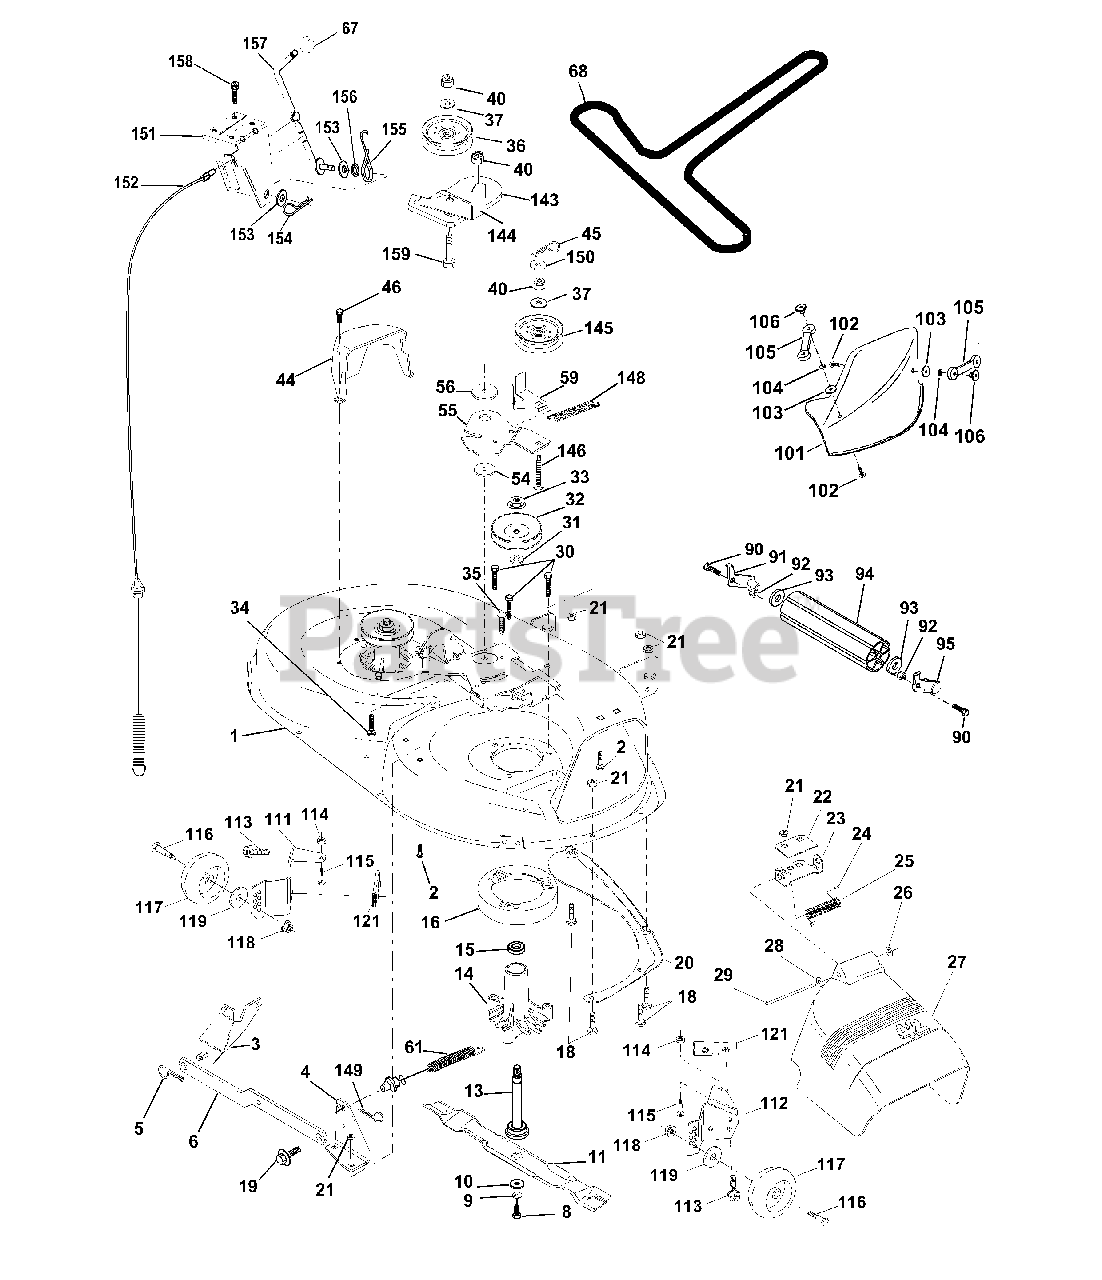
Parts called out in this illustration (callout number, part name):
1	Mower Deck Assembly, 42"
2	Bolt
3	Bracket Asm Fr. Sway Bar 3/42
4	Bracket Asm Deck 42" Sway Bar
5	Retainer Spring
6	Arm, Suspension, Rear
8	Bolt 3/8-24 x 25 Grade 8 patched
9	Washer, Lock
10	Washer,Hardened
11	Blade, Mulching 42"
11	Blade Mower 42" Hi-Lift
13	Shaft Assembly, Mandrel, Vented
14	Housing, Mandrel, Vented
15	Bearing, Ball, Mandrel
16	Stripper, Mandrel Deck
18	Bolt, Carriage 5/16-18 x 5/8
19	Bolt, Shoulder
20	Baffle, Vortex
21	Nut
22	Stiffener Bracket
23	Bracket, Deflector Mower 42"
24	Cap, Sleeve 80 x 112 Blk Mower
25	Spring, Torsion, Deflector 2 52
26	Nut, Push Phos & Oil
27	Shield, Deflector 42" Blk
28	Washer 11/32 x 5/8 x 16 Gauge
29	Rod, Hinge 42" 6 75 W/G
30	Screw Thdrol Washer Head
31	Washer, Spacer Mower Vented
32	Pulley, Mandrel
33	Nut, Toplock 9/16
34	Bolt
35	Fastener, Christmas Tree
36	Pulley, Idler, Flat
37	Washer 13/32 x 13/16 x 16 Gauge
40	Nut
44	Guard, Mandrel, LH
45	Retainer
46	Screw, Thdrol 1/4-20 x 5/8 T
48	Washer,Hardened
49	Roller Assembly, Cam Follower
50	Bolt, Shoulder #10-24 Grade 5
51	Locknut
52	Bolt, Shoulder 5/16-18 UNC
53	Arm Assembly, Pad, Brake
54	Washer,Hardened
55	Arm, Idler
56	Spacer, Retainer
59	Guard TUV Idler
67	Knob
68	V-Belt, 42" Mower
90	Bolt Fin Hex 3/8-16 Unc x 1
91	Bracket Asm. Noseroller LH
92	Nut, Lock, Hex W/Ins 3/8-16 UNC
93	Washer 17/32 x 7/8 x 16 Ga.
94	Roller, Nose
95	Bracket Asm. Noseroller RH
101	Mulcher Cover
102	Screw
103	Washer, Flat
104	Washer, Lock
105	Latch Assembly
106	Nut, Weld
111	Bracket, Gauge, Wheel LH
112	Bracket, Gauge, Wheel RH
113	Screw Tapping 5/16-18 Unc
114	Nut, Keps 5/16 - 18 UNC
115	Bolt, Carriage 5/16-18 x 1/2
116	Bolt, Shoulder
117	Wheel, Gauge
118	Nut Centerlock 3/8-16
119	Washer 3/8 x 7/8 x 14 Ga.
121	Bracket, Extruded
142	Arm Spring Brake Mower
143	Bracket Arm Idler 42"
144	Keeper Belt 42" Clutch Cable
145	Pulley Idler Flat
146	Bolt Carriage Idler
147	Spring Extension
148	Spring Return Idler
149	Retainer Spring Yellow
150	Washer 9/32 x 3/4 x 16 Ga.
151	Bracket Clutch Cable
152	Clutch Cable 42"
153	Washer Flat 3/8" Type B
154	Spring Retainer
155	Spring Retention LVR CLTCH CAB
156	Spacer Clutch Cable
157	Rod Clutch Cable 3/8"
158	Screw Hex Thd Cut 1/4-20 x 5/8
159	Bolt Rdhd Sqn 3/8-16 UNC x 1-3/4
